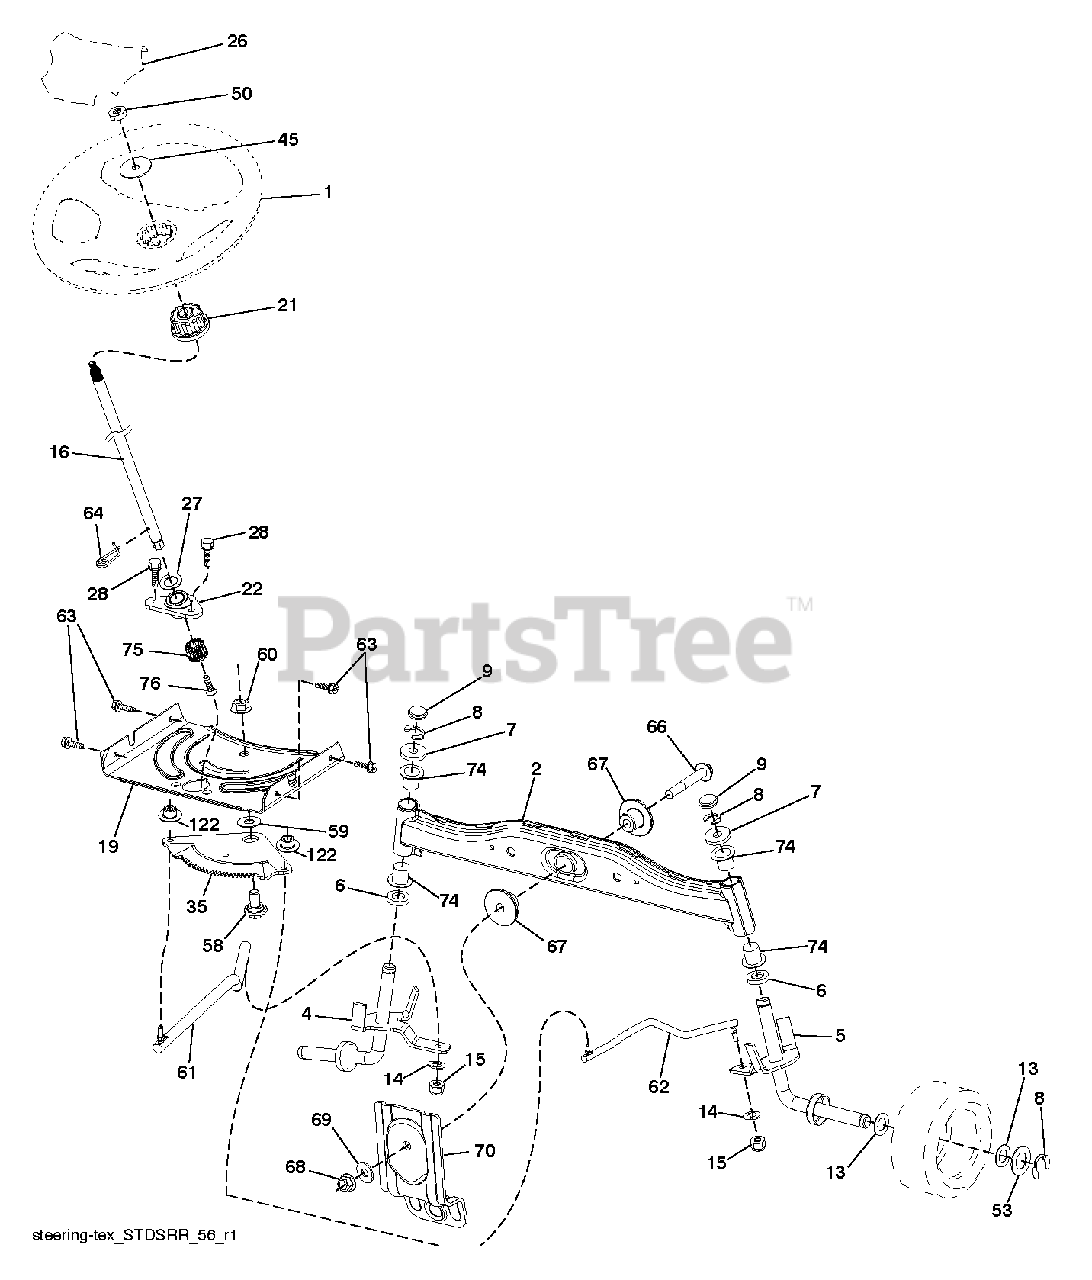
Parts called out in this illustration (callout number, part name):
1	WHEEL.STEERING.HUSQ.PREM.HRDRM
2	AXLE HALF ASM-WELDED
4	SPINDLE.WELDED.LH.15"TEX
5	SPINDLE.WELDED.RH.15"T
6	THRUST WASHER
9	CAP.SPINDLE.BLACK
14	WASHER, LOCK 3/8
15	NUT CROWNLOCK 3/8-24
16	SHAFT.STEER.2HIGH.SPLND.PLATED
19	PLATE.STEER.DDL.NLT/NG
21	ADAPTER.WHEEL.STEER.SPLND.ALUM
22	BEARING.SHAFT.STEER.LOWER.625
26	INSERT.CAP.WHL.STRG.HUSQ.PREM
28	SCREW, 3/8-16X3/4
35	GEAR.SECTOR.PLATE.DDL.
45	WASHER 9/16"ID, 2 3/8"OD
50	NUT LOCK FLG 3/8-16 UNC
53	WASHER.HARDENED
58	BOLT.SHOULDER.SECTOR.P
59	WASHER.THURST.SECTOR.S
60	NUT FLANGE LOCK 5/8-11
61	DRAGLINK.LH.BALLSTUD.D
62	DRAGLINK.RH.BALLSTUD.D
63	SCREW
64	RETAINER.CLIP.SPRING.S
66	BOLT HEX FGHD 7/16-14 X 3 SERR
67	BUSHING.PM.FRONT AXLE
68	NUT.LOCK.FLANGE.7/16
69	WASHER.1.5X.505X.118
70	BRACKET.FRT.DECK.SUSP.RR.MT431
74	BRNG T
75	PINION.ZINC PLATED
76	SCREW HEAD SOCKET LRVB
122	CAP.GEAR.SECTOR.TEX
